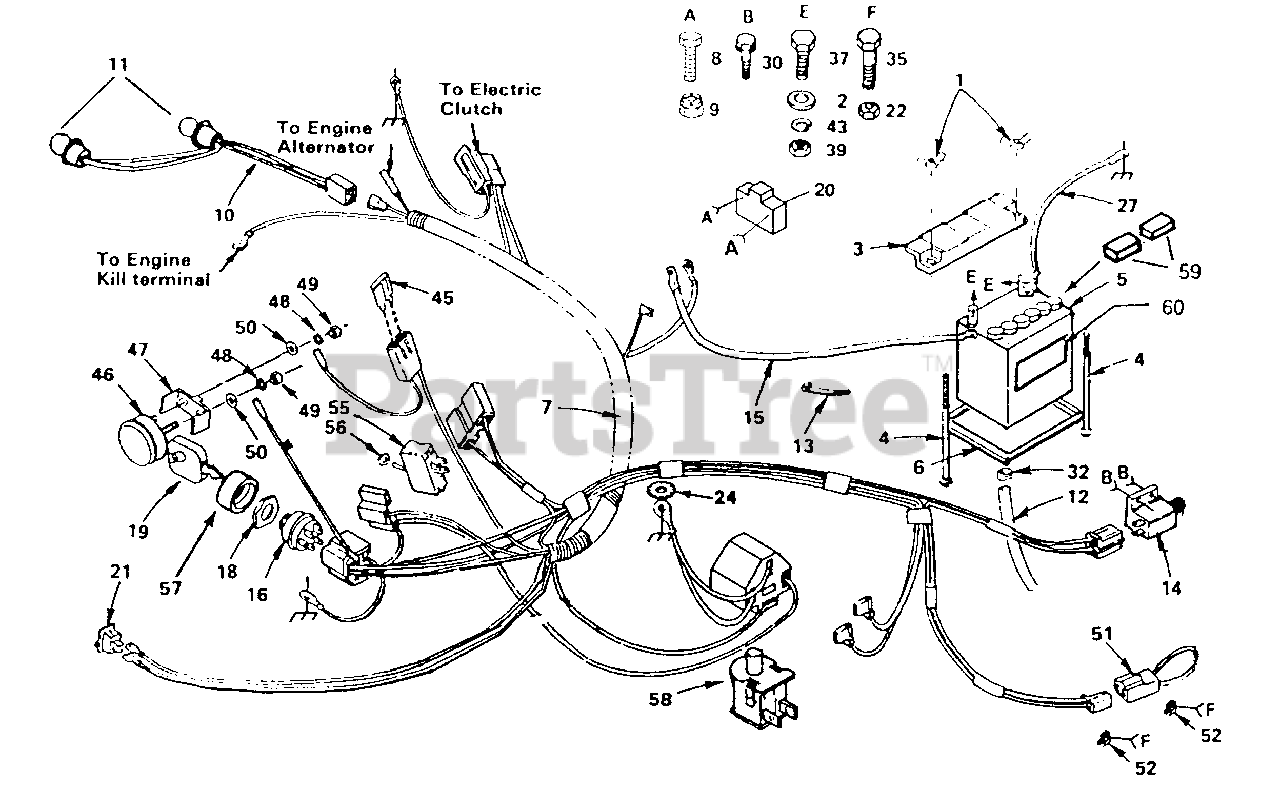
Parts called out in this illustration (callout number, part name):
1	Wing Nut, 1/4-20
2	Washer, 9/32 x 5/8 x 16 Ga
3	Guard, Terminal
4	Battery Bolt, Carriage 1/4-20 x 7-1/2
5	Battery
6	Battery Tray
7	Harness, Ignition
8	Nut, Crownlock 1/4 - 20
9	Bolt, Hex Fin 1/4 - 20 x 1
10	Harness, Light Socket
11	Bulb, Light
12	Tube, Battery Tray
13	Cable Tie
14	Switch, Interlock, Clutch
15	Cable, Battery (Battery to Solenoid)
16	Ignition Switch
18	Nut, Ignition
20	Regulator
21	Switch, Light
22	Nut, Crownlock 1/4-20
24	Washer, Lock, Ext. Tooth - 3/4
27	Cable, Battery (Battery to Ground)
30	Screw, Tap. Hex Hd. No. 10-24 UNC
32	Clamp, Hose
35	Bolt, Hex 1/4-20 x 1/2 Gr. 5
37	Bolt, Hex 1/4-20 x 3/4
39	Nut, Hex 1/4-20
43	Lockwasher, 1/4
45	Fuse, 30 Amp.
47	Bracket, Ammeter
48	Lockwasher, No. 10
50	Washer, 7/32 x 1/2 x 18 Ga.
51	Loop, Wire Tiller Attachment
52	Clip, Insulated
55	Switch, PTO
56	Nut, Hex
57	Bezel, Ignition
58	Switch, Plunger
59	Caps, Battery Set
60	Decal, Battery
